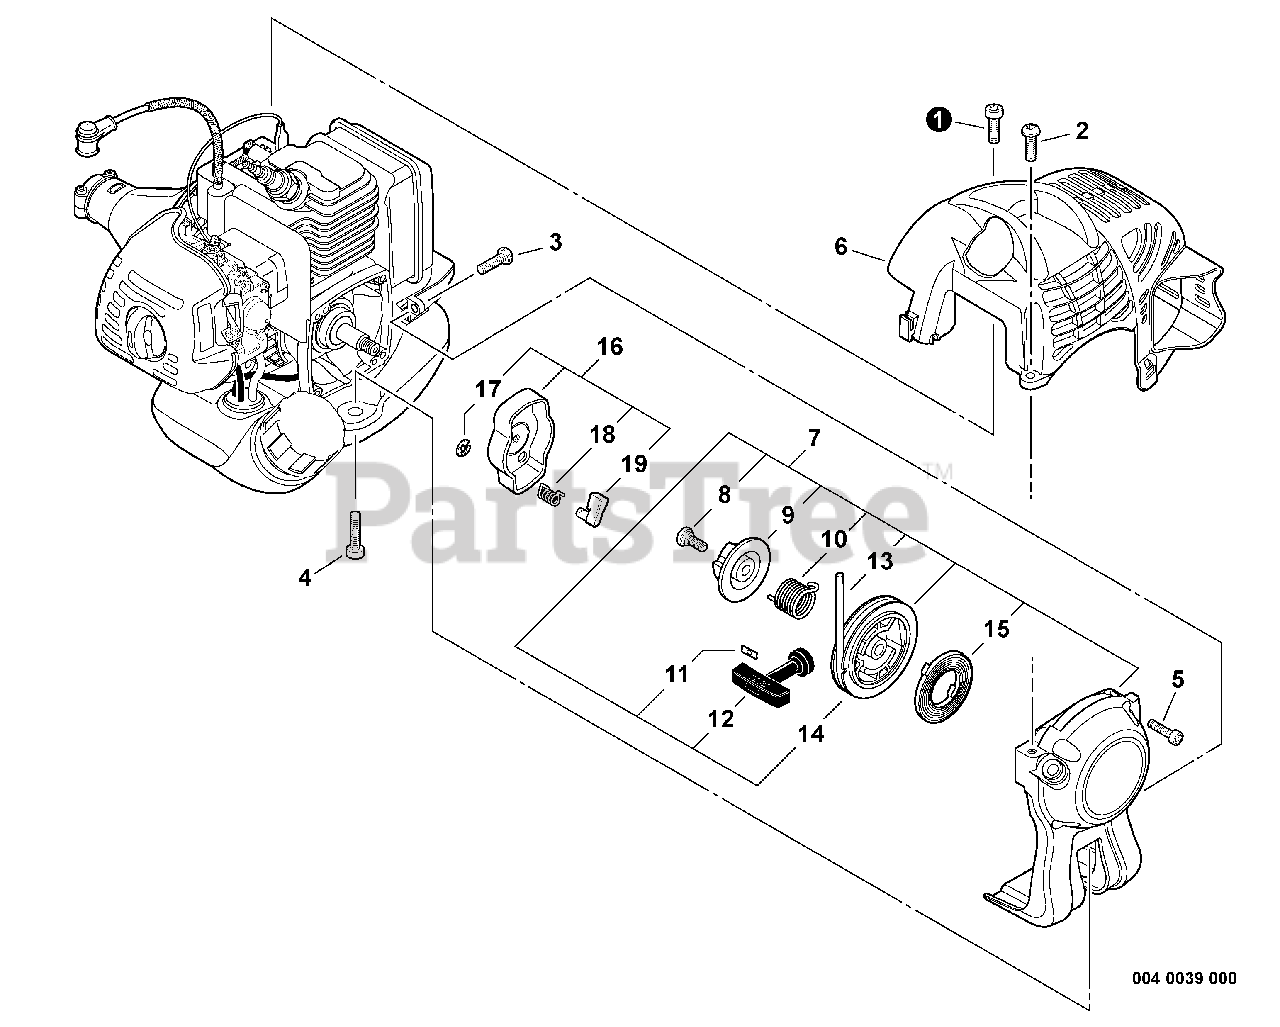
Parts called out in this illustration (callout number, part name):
1	BOLT, TORX 5×16
2	BOLT, TORX 5×16
3	BOLT, TORX 5×16
4	BOLT, TORX 5×20
5	BOLT, TORX 4×16
6	COVER, ENGINE
7	STARTER ASSY, RECOIL
8	SCREW
9	PLATE, CAM (NLA SEE PB 15-06)
10	SPRING, TORSION
11	RETAINER, ROPE
12	GRIP, STARTER
13	ROPE, STARTER
14	REEL, ROPE
15	SPRING, RECOIL
16	PAWL ASSY, STARTER
17	E-RING 4
18	SPRING, RETURN
19	PAWL, STARTER
